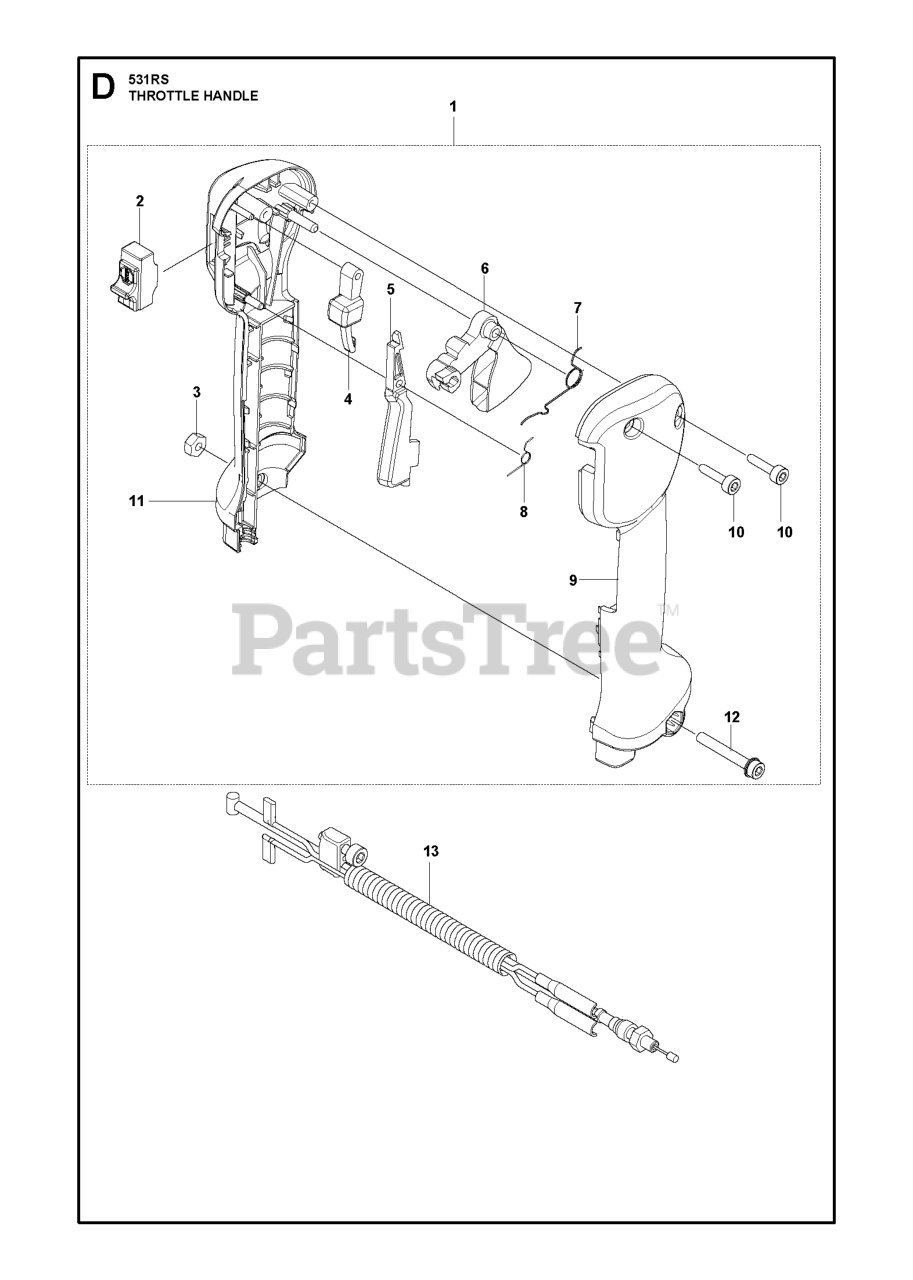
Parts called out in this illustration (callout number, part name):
2	START/STOP SWITCH
4	STARTER THROTTLE LOCK
5	THROTTLE LOCKOUT
6	THROTTLE CONTROL
10	SCREW IHSCT MT4X18 10.9 ZN/FE
12	SCREW IHSCFM
